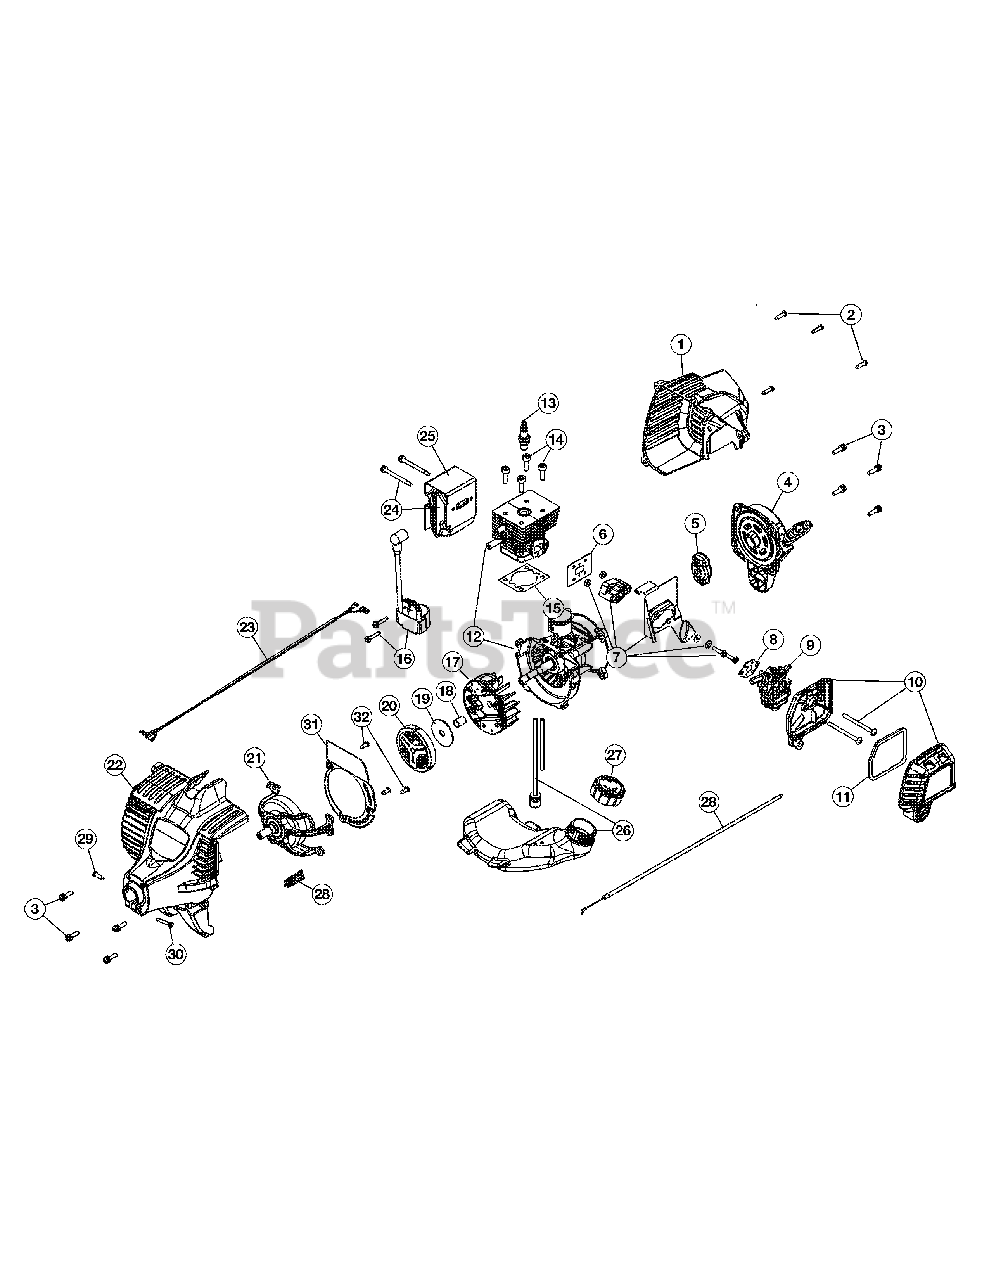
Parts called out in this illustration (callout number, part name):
1	Rear Cover Assembly
3	Screw
4	Starter Assembly
5	Pawl Assembly
6	Insulator Gasket
7	Insulator Assembly
8	Carburetor Gasket
9	Carburetor Assembly
10	Aircleaner Assembly
11	Air Filter
12	Shortblock Assembly
13	Spark Plug
14	Screw
15	Cylinder Gasket
16	Module Assembly
19	Washer
21	Frame w/ Clutch Drum
22	Clutch Cover Assembly
23	Lead Wires
24	Muffler Assembly
25	Muffler Gasket
26	Fuel Tank
28	Throttle Cable Assembly
29	Screw
30	Screw
31	Pressure Plate Assembly
32	Screw
